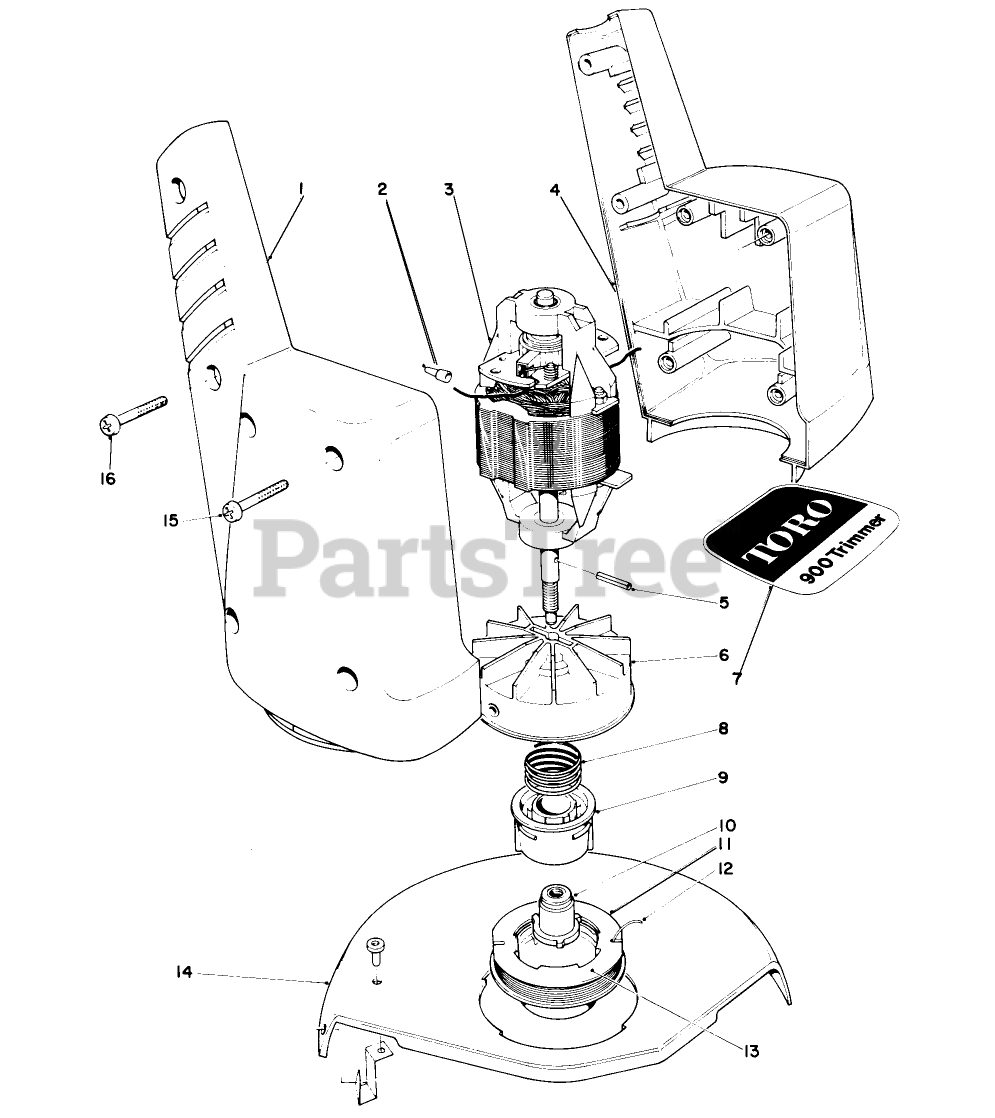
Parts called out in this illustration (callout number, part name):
1	Right Motor Housing
2	CONNECTOR WIRE JOINT
3	Motor
4	Left Motor Housing
5	COIL PIN
6	FAN HUB ASM
7	Toro 900 Decal
8	SPRING-COMPRESSION
9	CORE - SPOOL
10	Driver
11	SPOOL CAP
12	.040" Cutting Line in Coil
13	Prewound Spool
14	Shield with Cut-off Blade
15	SCREW-PPH
